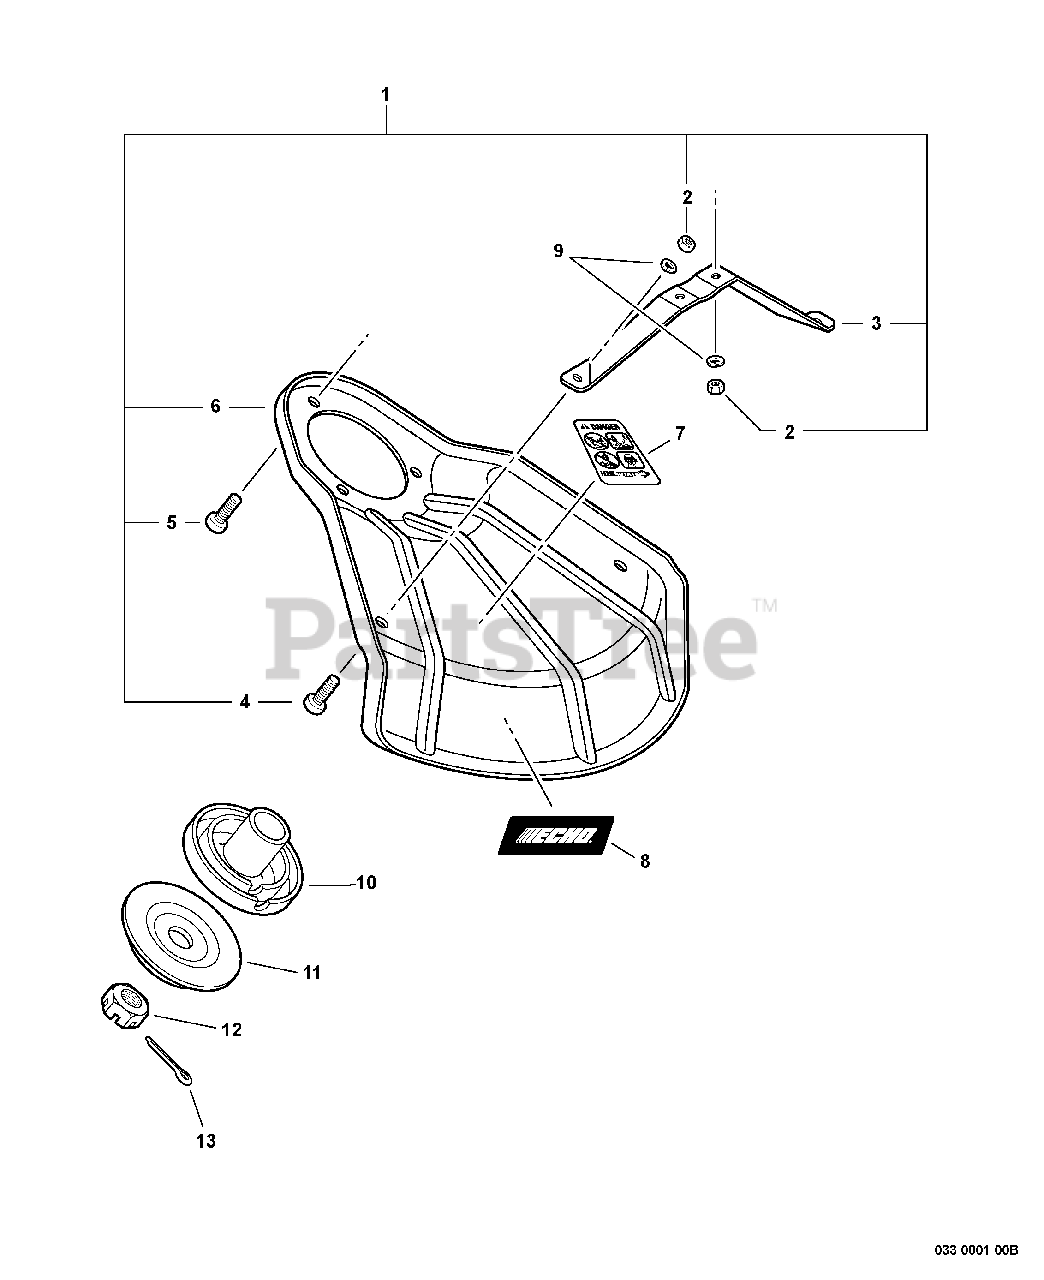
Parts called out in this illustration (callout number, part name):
1	DEBRIS SHIELD KIT
2	NUT, LOCK M5
3	BRACKET, SHIELD MOUNTING
4	SCREW 5×8
5	SCREW 5×10
6	SHIELD, METAL DEBRIS
7	LABEL, DANGER
8	LABEL, ECHO
9	WASHER, SPRING 5
10	PLATE, ADAPTOR - UPPER
11	PLATE, ADAPTOR - LOWER
13	PIN, COTTER 2×22
